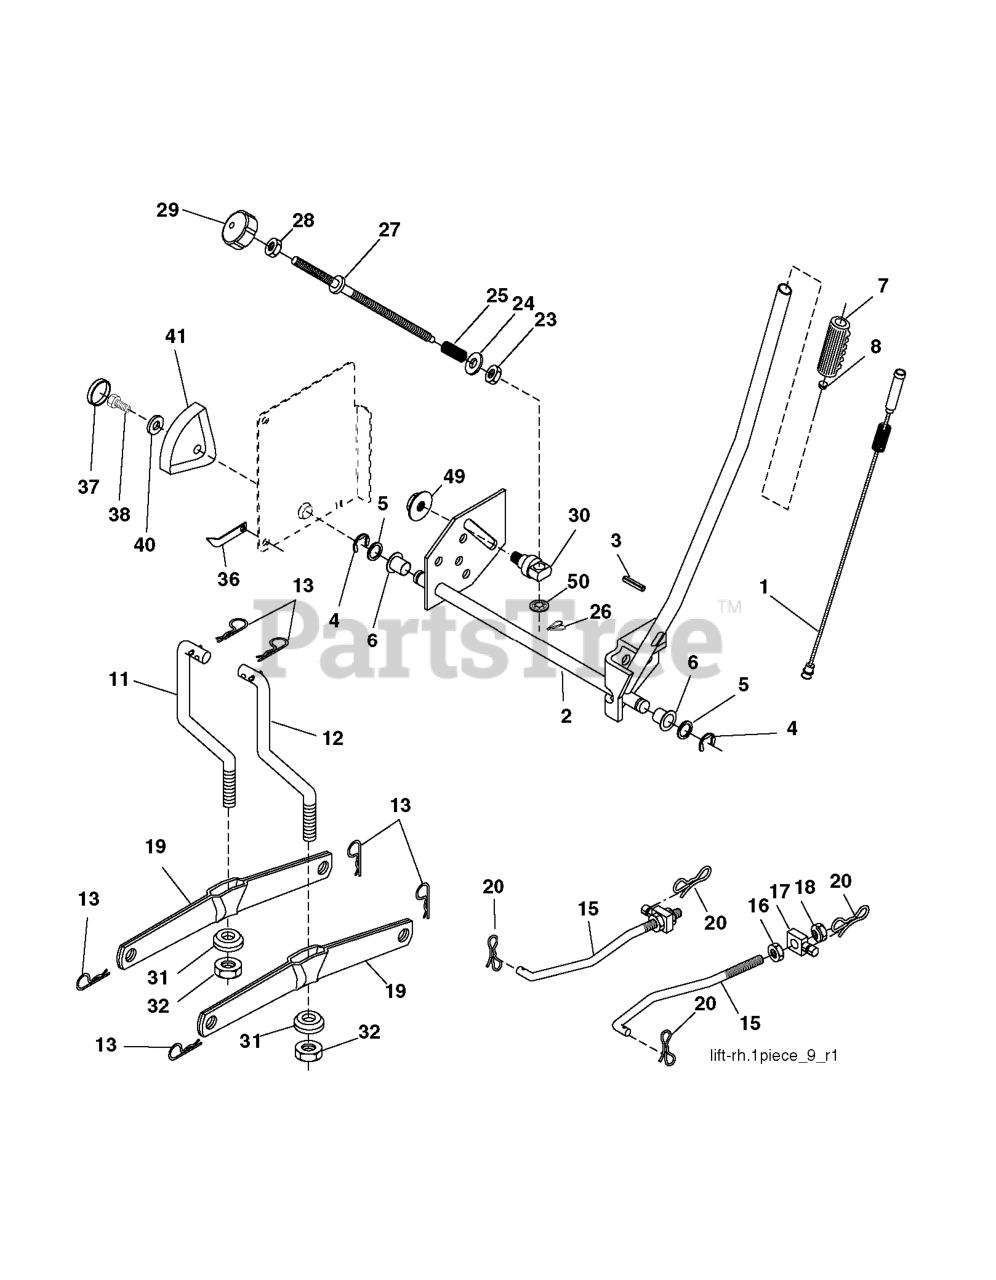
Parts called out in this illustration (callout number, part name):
1	WIRE ASM INNER W/ PLUNGER LT
2	SHAFT ASM R HANDLE
3	PIN GROOVE.
4	RETAINING RING LT
6	BEARING.NYLON
7	GRIP HANDLE
8	REPL BY 532 12 59-25
11	LINK
12	LINK
13	RETAINER-SPRNG RB
15	LINK.SUSPENSION.FRONT
16	NUT.HEX.JAM.1/2-13
18	NUT.LK.W/WSH.1/2.
19	ARM.REAR.SUSPENSION
20	PIN.COTTER.7/16.BOW TI.
26	RETAINER CLIP
27	ROD ADJ LIFT
28	NUT
29	KNOB INF 3/8-16
31	BEARING.PIVOT.LIFT
32	NUT CROWNLOCK 3/8-24
36	POINTER, HEIGHT INDICATOR(2 2)
38	SCREW 5/16-18X1
41	HEIGHT INDICATOR
49	NUT
50	NUT PUSH M
